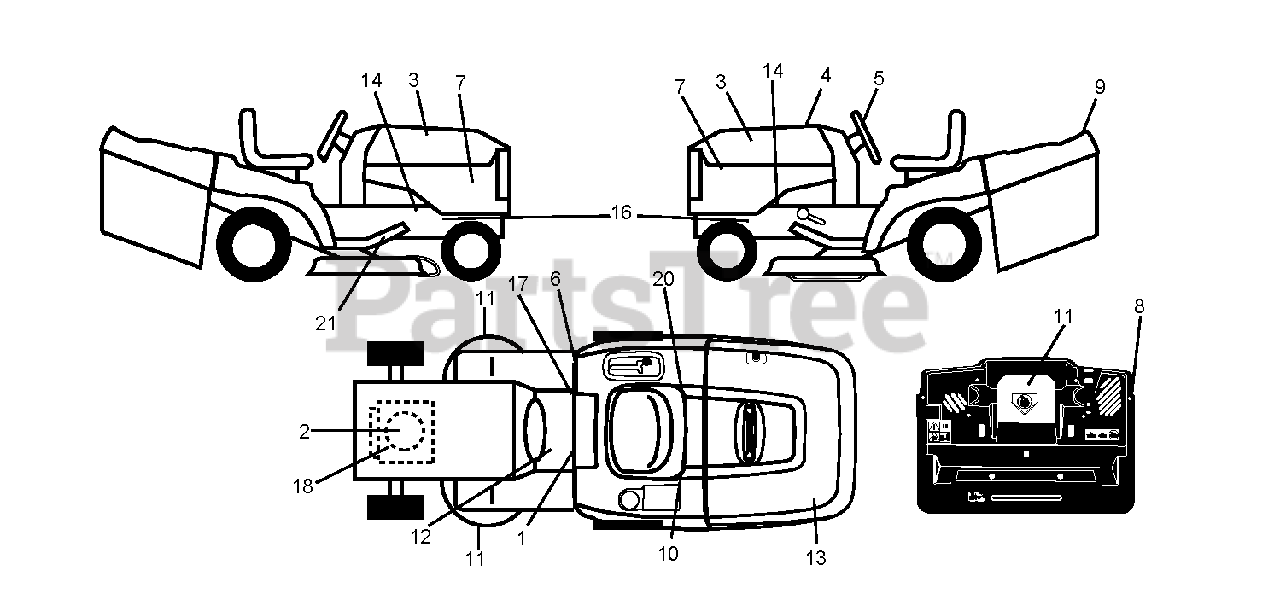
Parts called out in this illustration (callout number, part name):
10	DECAL BTRY SYMBOLS
11	DECAL.INTERNATIONL.CUTFINGER
17	DECAL PARK BRAKE
20	DECAL.BYPASS.FENDER.CRD.LT.YT
